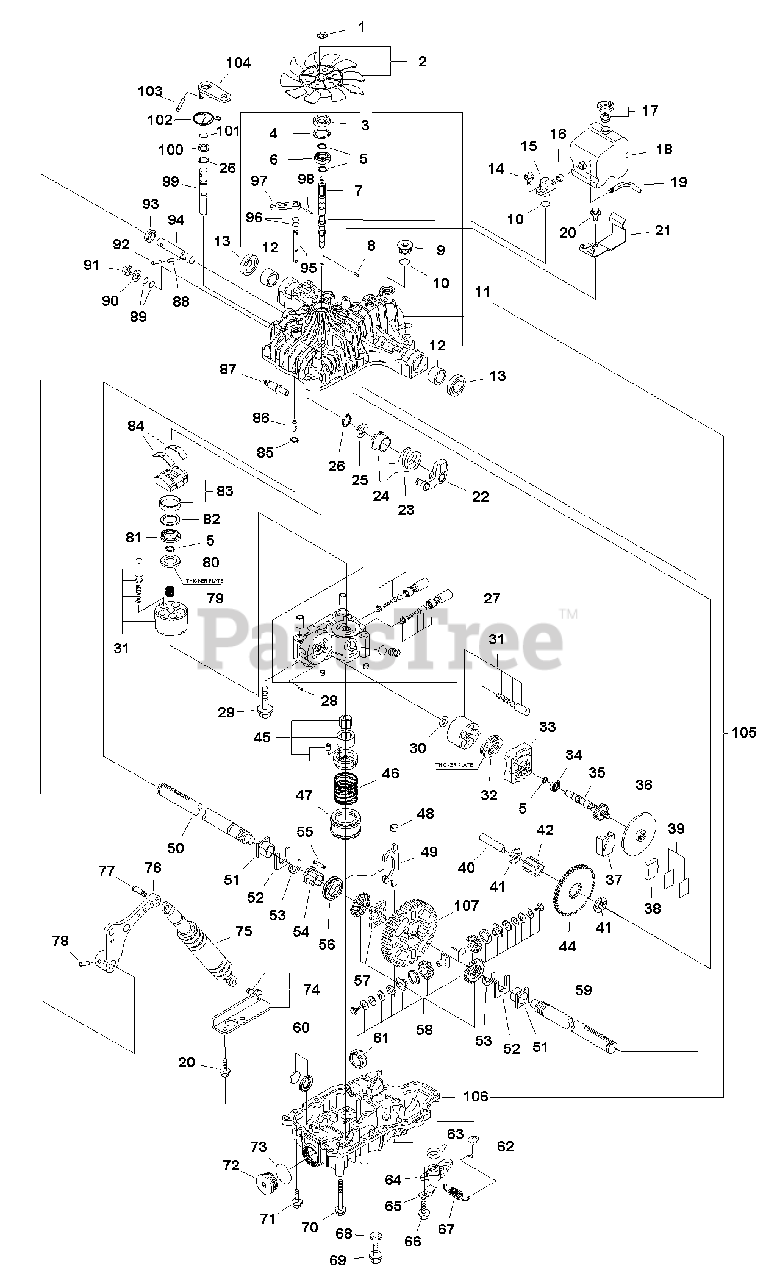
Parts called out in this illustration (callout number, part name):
1	RING E15
2	FAN
3	SEAL
4	RING 35
5	RING 15
6	BEARING 6202UC3
7	SHAFT, PUMP
8	PIN 3 x 13.8
9	CAP, M20B
10	O-RING, P18
11	HOUSING, UPPER
12	BUSHING, 25.4
13	SEAL S25.4 x 42 x 8
14	BOLT, 8 x 20
15	FITTING
16	SEAL, 8
17	VALVE, VENT 15
18	TANK, RESERVOIR
19	PIPE, 8
20	SCREW, TAPPING
21	BRACKET, TANK
22	ARM, CONTROL
23	SPRING, TORSION
24	COLLAR, CONTROL
25	WASHER 17 x 30 x 1
26	RING
27	CASE, CENTER
28	PIN 3 x 9.8
29	BOLT, 10 x 65
30	WASHER 12 x 24 x 1
31	CYLINDER BLOCK
32	BEARING, THRUST
33	HOUSING
34	BEARING, 6302UC3
35	SHAFT, MOTOR
36	DISC, BRAKE
37	ACTUATOR, BRAKE
38	SHOE, BRAKE
39	SHIM SET
40	SHAFT, FINAL PINION
41	WASHER, 15 x 32 x 3.2
42	PINION, FINAL
44	GEAR, REDUCTION
45	PUMP, CHARGE
46	SPRING, CHARGE PUMP
47	FILTER (25)
48	FORK, PIVOT
49	FORK, DIFF LOCK
50	SHAFT, AXLE RH #1
51	BUSHING
52	THRUST WASHER
53	RING
54	COLLAR, 25.4
55	PIN, DIFF LOCK
56	SLIDER, DIFF LOCK
57	PLATE, DIFF LOCK
58	DIFFERENTIAL GEAR KIT
59	SHAFT, AXLE LH #1
60	MAGNET
61	FILTER (25)
62	HOOK, SPRING
63	PACKING, 1AG25
64	ARM, DIFF LOCK
65	PLATE, ARM
66	BOLT 10 x 12
67	SPRING, RETURN
68	WASHER, SEAL
69	BOLT 10 x 12
70	BOLT, 8 x 75
71	SCREW, TAPPING
72	CAP (M40)
73	PACKING 1A 2040
74	STAY
75	SHOCK ABSORBER
76	LEVER, CONTROL
77	PIN
78	PIN, 3.5 x 25
79	PUMP SHAFT
80	THRUST PLATE A
81	BEARING K81106
82	THRUST PLATE B
83	PLATE, SWASH
84	THRUST METAL
85	RING
86	SPRING
87	FULCRUM, ECCENTRICIT
88	PIN 6.0A x 25
89	PACKING
90	WASHER
91	NUT 12
92	PIN, 4 x 28
93	SEAL TC162606
94	SHAFT, CONTROL
95	SHAFT (BYPASS)
96	PACKING
97	LEVER, BYPASS
98	PIN 3.0A x 20
99	SHAFT, BRAKE HL #10
100	WASHER, 16 x 23 x 1.6
101	PACKING
102	SPRING, BRAKE
103	PIN 6.0A x 4.0
104	ARM, BRAKE
105	HOUSING, COMPLETE SET
106	HOUSING, LOWER
107	GEAR, FINAL
